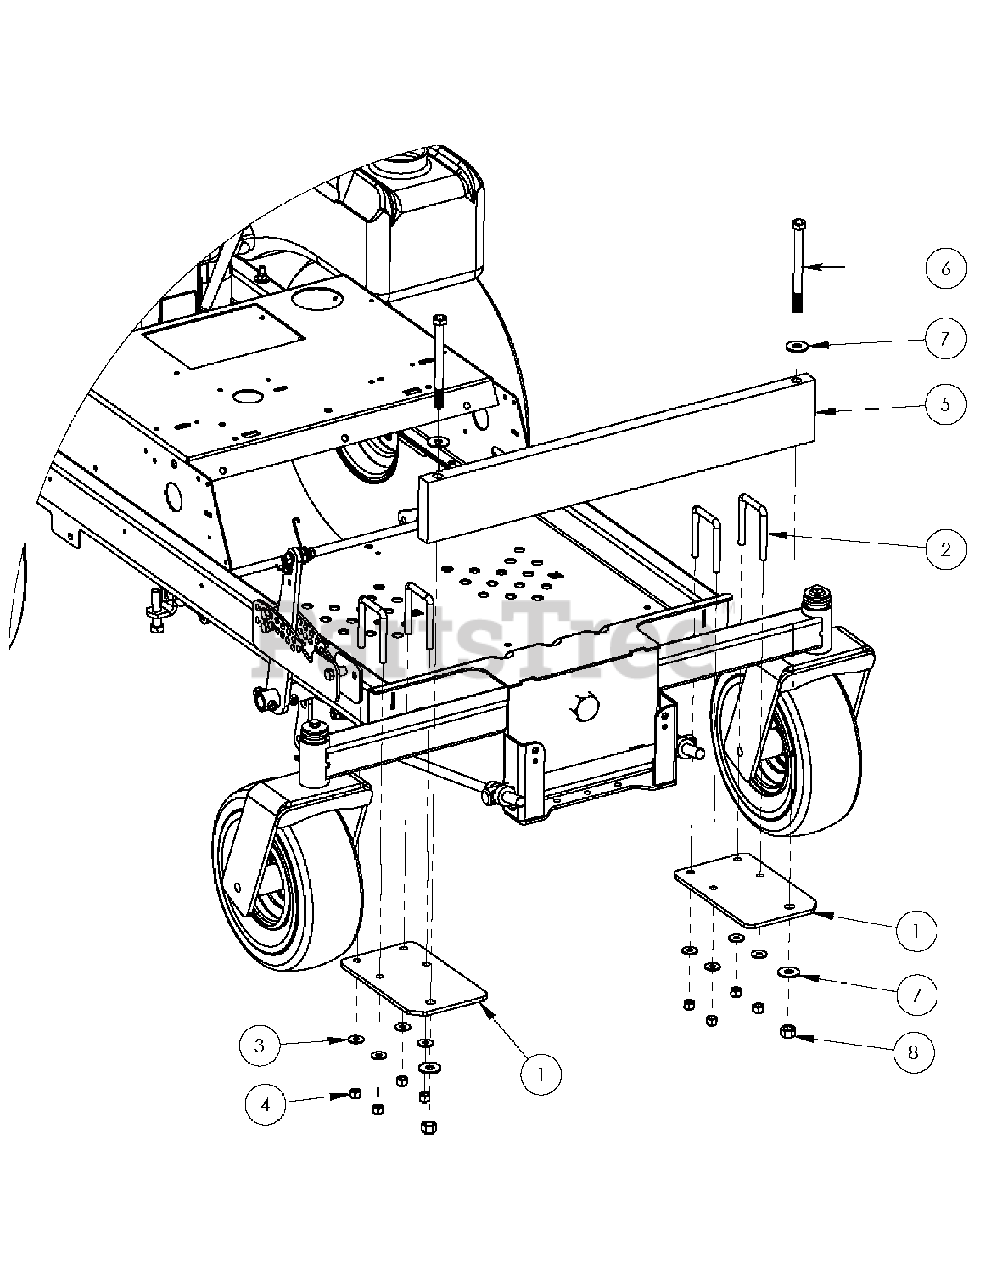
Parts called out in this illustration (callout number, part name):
1	WEIGHT BRACKET
3	FLAT WASHER-5/16"
4	HEX NUT, NYLON INSERT-3/8"-16
5	BAR, WEIGHT-
6	CAP SCREW, 1/2"-13 X 5 1/2" LONG
7	FLAT WASHER-1/2"
8	HEX NUT, NYLON INSERT-1/2"-13
